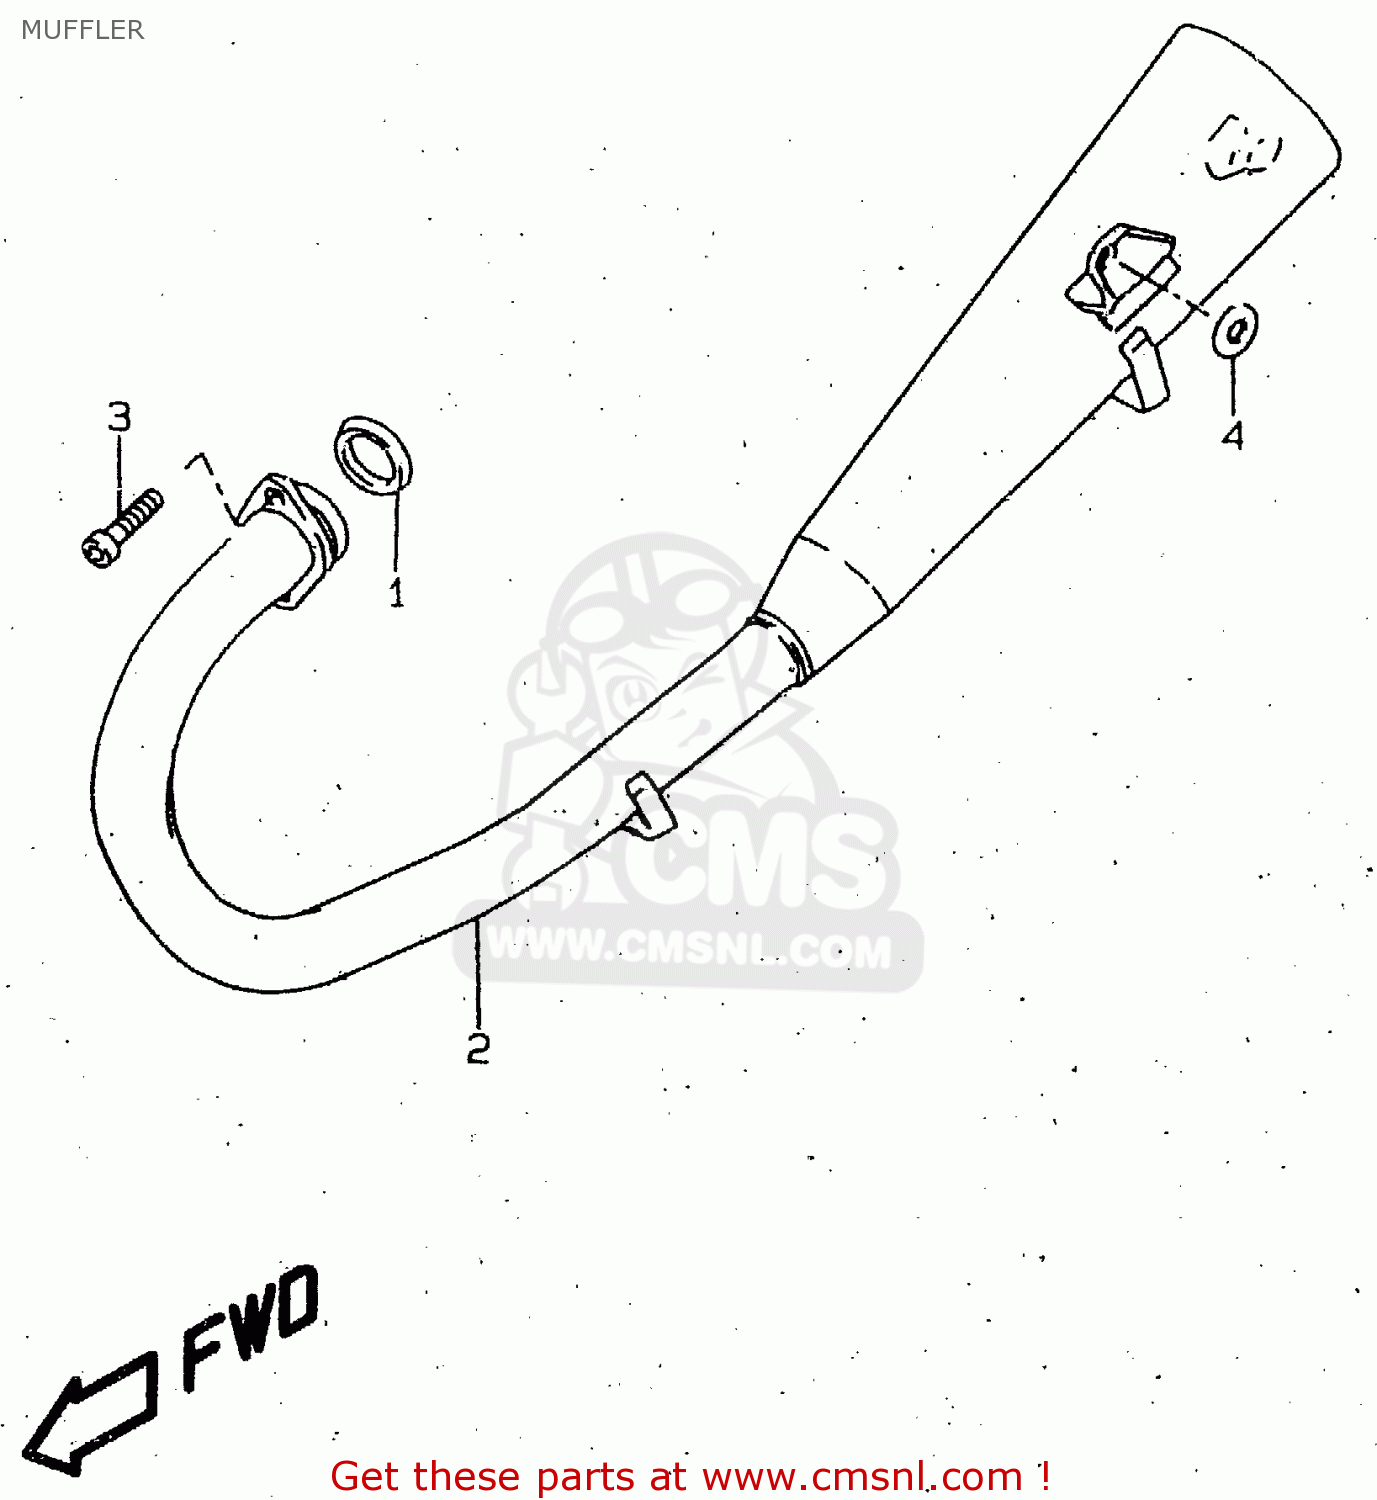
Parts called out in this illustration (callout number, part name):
1	GASKET, EXHAUST PIPE
2	MUFFLER
3	BOLT
4	WASHER
